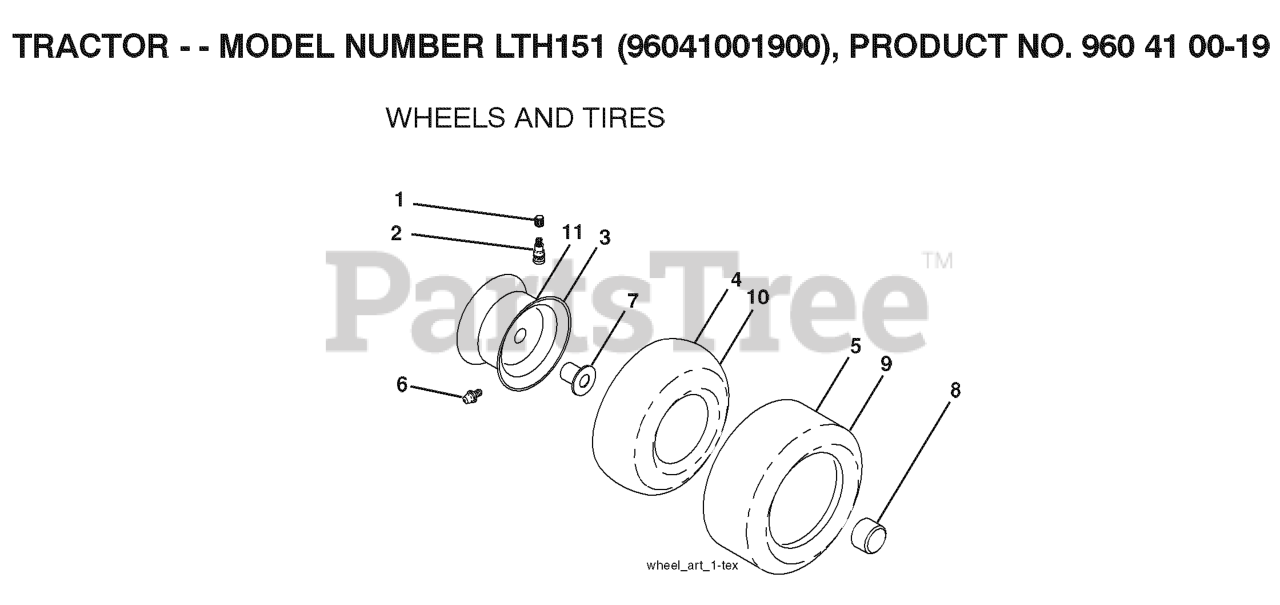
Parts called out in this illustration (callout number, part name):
2	VALVE STEM LT
3	RIM ASM 6" FRONT SILVER
4	TUBE.5.3/4.5/6
5	TIRE HEAVY DUTY
6	FITTING LT
7	BEARING T
8	CAP, AXLE BLK
9	TIRE HEAVY DUTY
10	TUBE
11	RIM ASM 8" REAR SILVER
